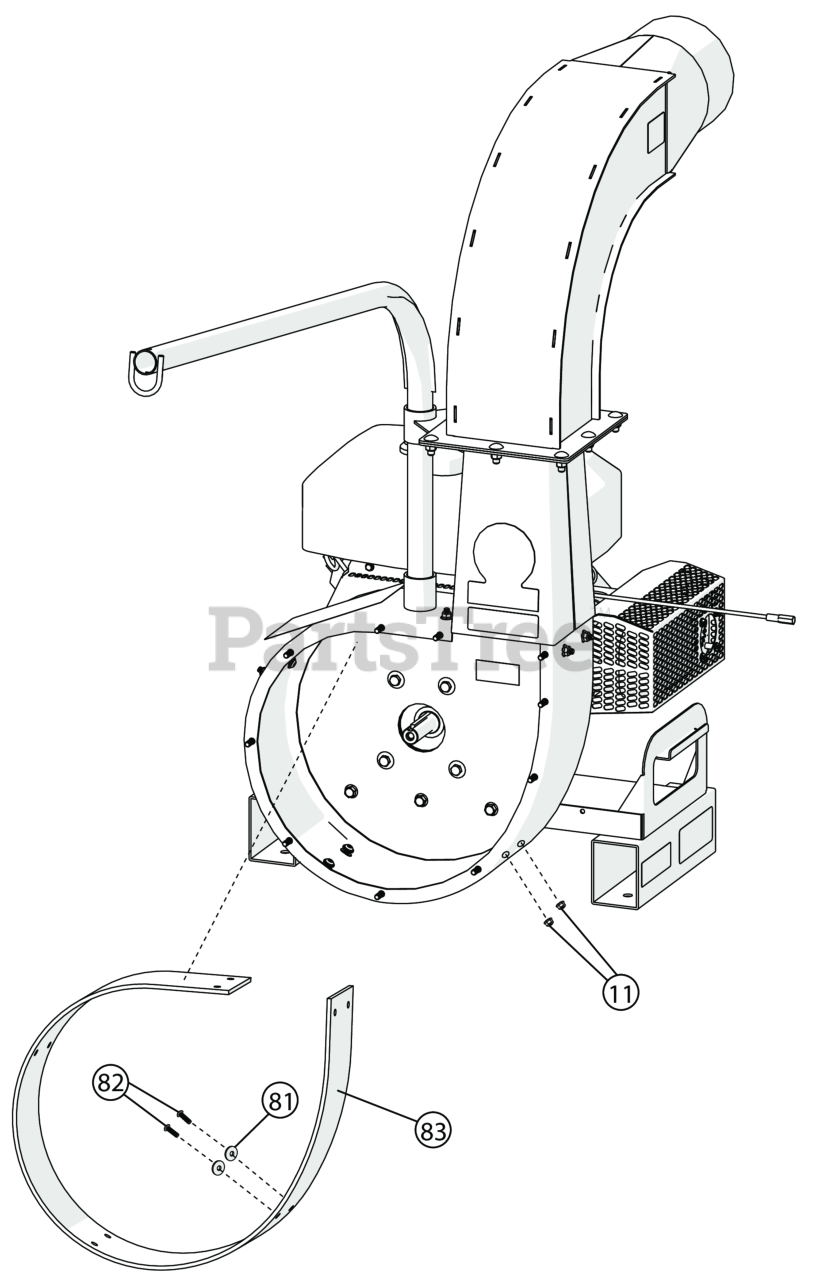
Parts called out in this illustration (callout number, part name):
11	NUT-HEX-NYLK, FLG .3125-18 ZP
81	WASHER 5/16" SAE Z/P
82	SCREW BUTTON HEAD 5/16"-18 X 1.00
83	LINER SMALL HOUSING DL18 (PLASTIC)
